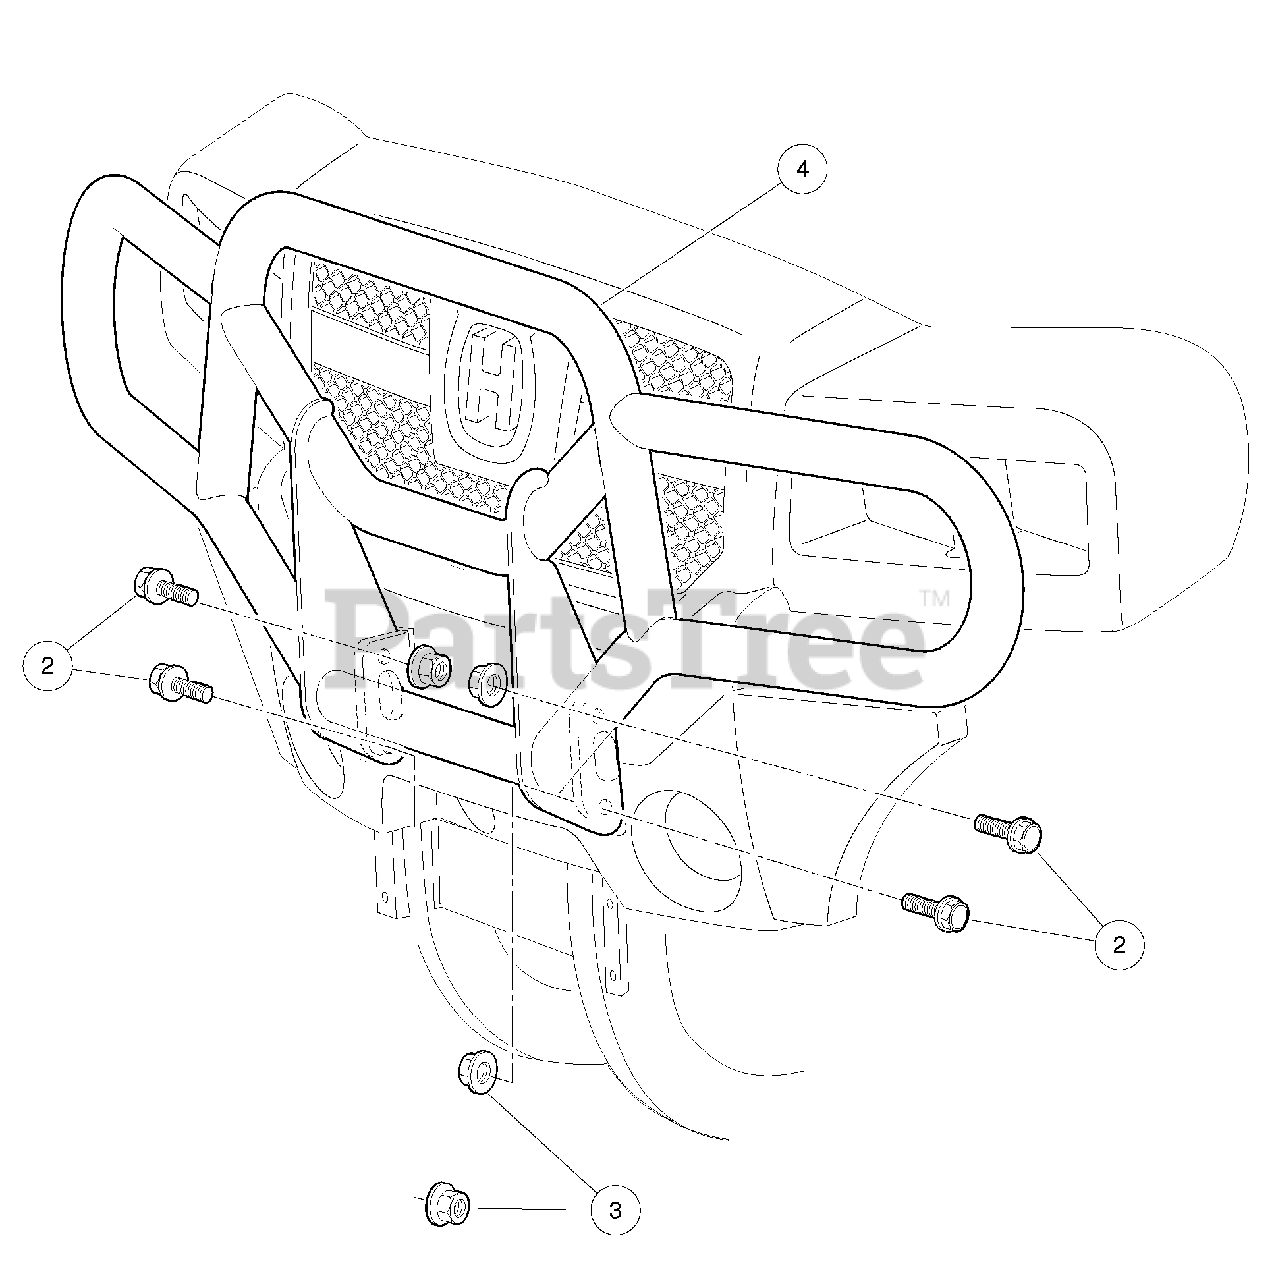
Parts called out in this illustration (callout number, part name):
1	Kit, Brush Guard Hus
2	Screw, M10 X 1.25 X 30 Hex Blk
3	Nut, Flg, M10 X 1.25 Hex Blk
4	Weldment, Brushguard, HUV 4421
